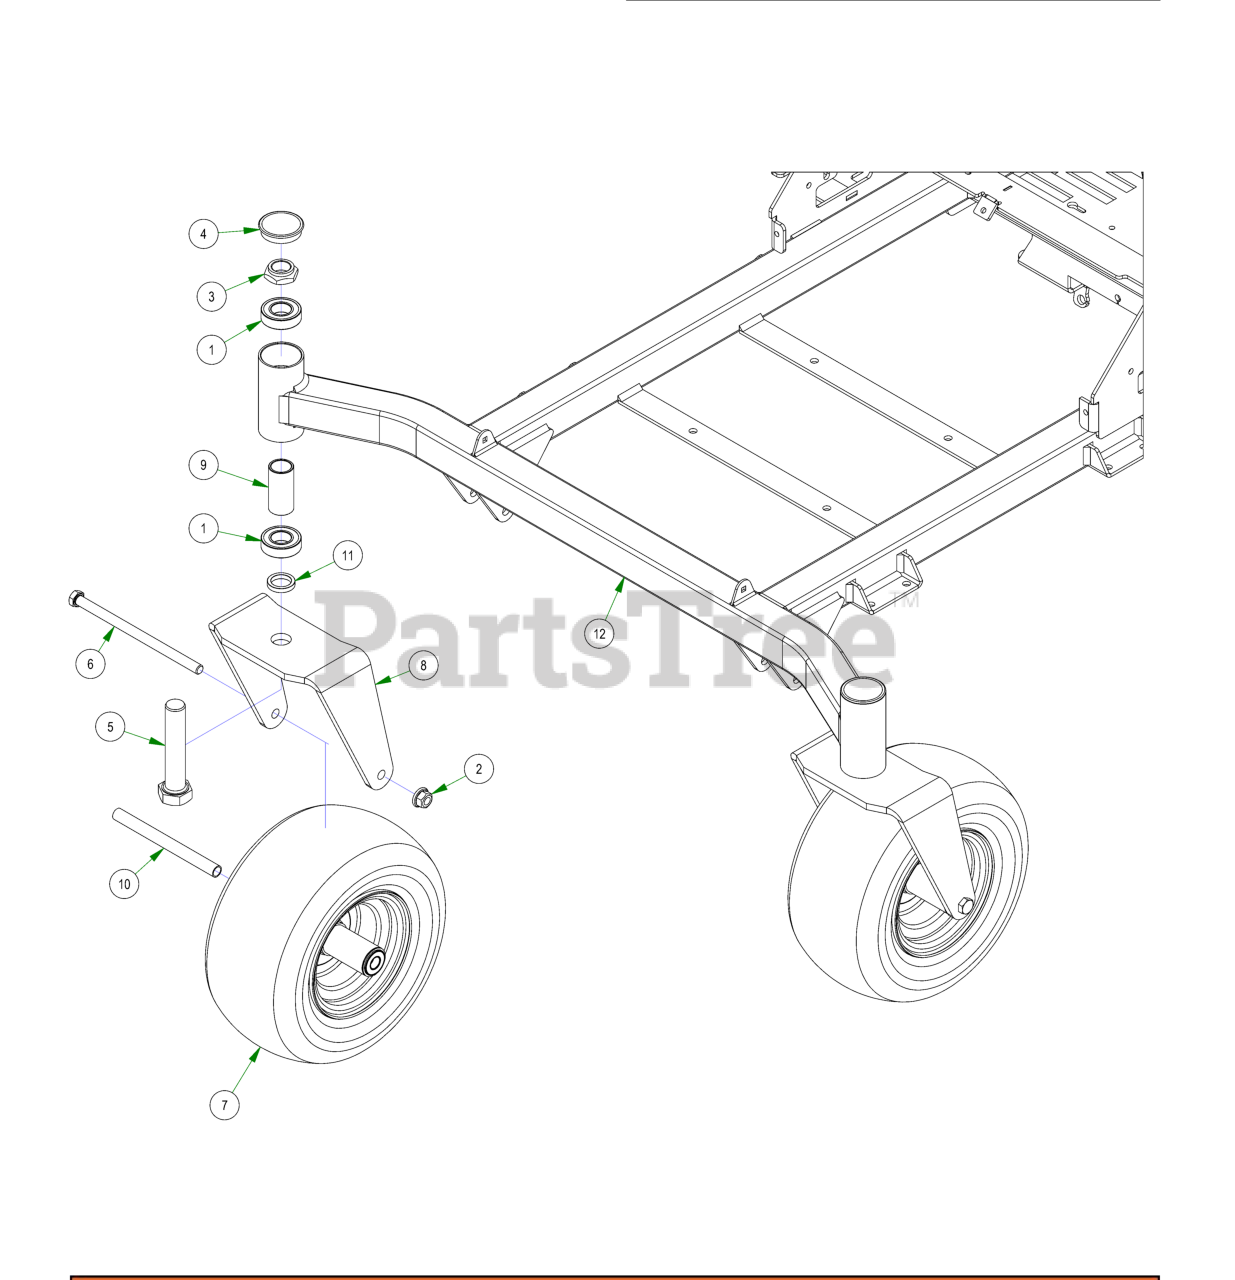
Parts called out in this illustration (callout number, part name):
1	1641 BEARING W/2 CONTACT RUBBER SEALS
2	1/2-13 NYLON INSERT FLANGE LOCKNUT ZINC
3	1"-14 NYLON INSERT JAM LOCKNUT ZINC
4	2017 Bearing Cover
5	1"-14 X 5 HEX CAP SCREW (GR.8) ZINC YELLOW
6	1/2-13 X 8-1/2 HEX CAP SCREW (GR.5) ZINC
7	12x6x6 Front Tire & Black Wheel Assembly (Representation Only)
8	2017 ZT Front Fork
9	2016 Front Bearing Spacer
10	Front Wheel Spanner
11	1.02 ID X 1.38 OD X .250 THK SPACER ZINC
12	2024 MZ-Avenger 54-60 Frame
